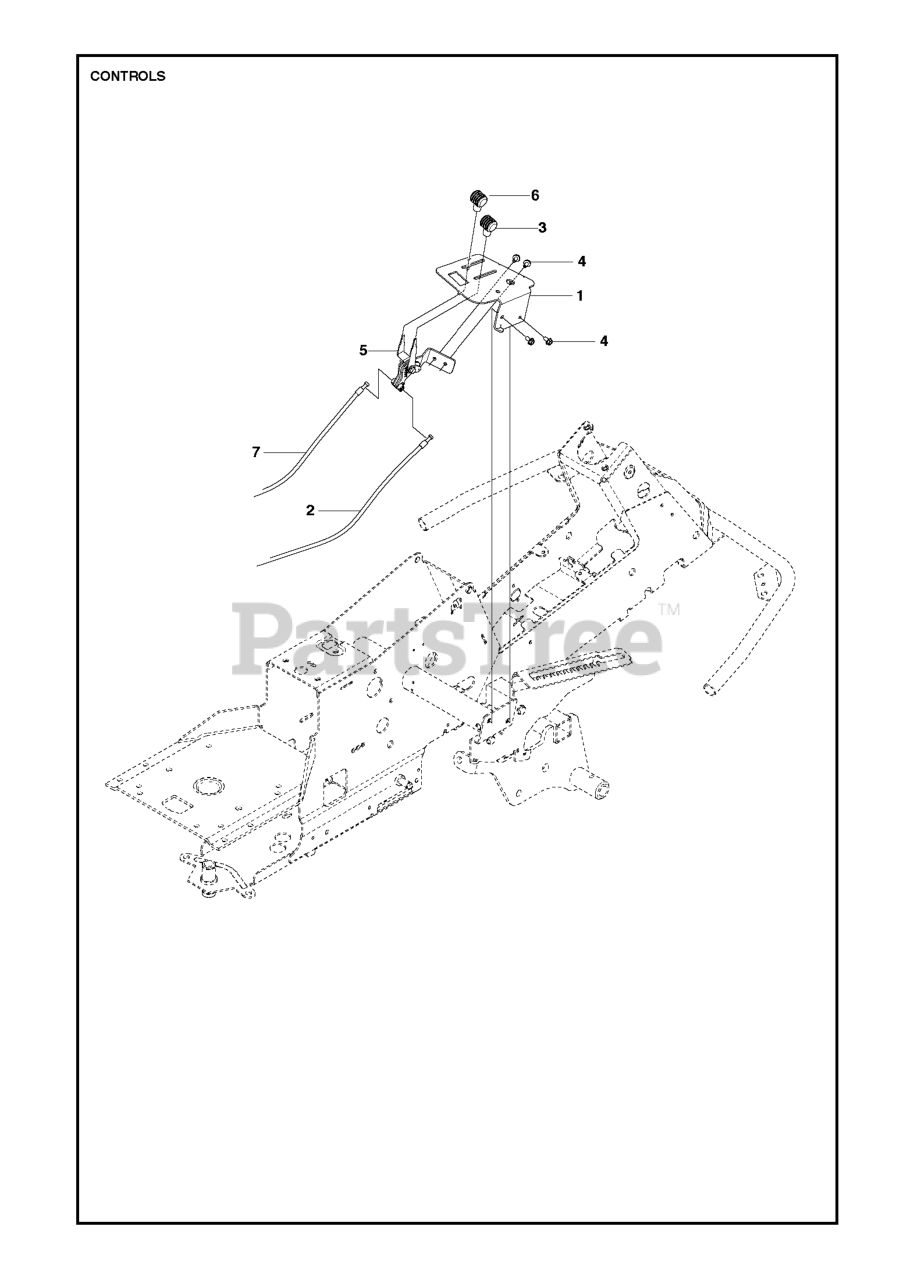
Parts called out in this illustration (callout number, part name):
2	WIRE
4	SCREW EHHFM
5	THROTTLE CONTROL
5	THROTTLE CONTROL ASSY SINGLE
6	KNOB
7	WIRE
